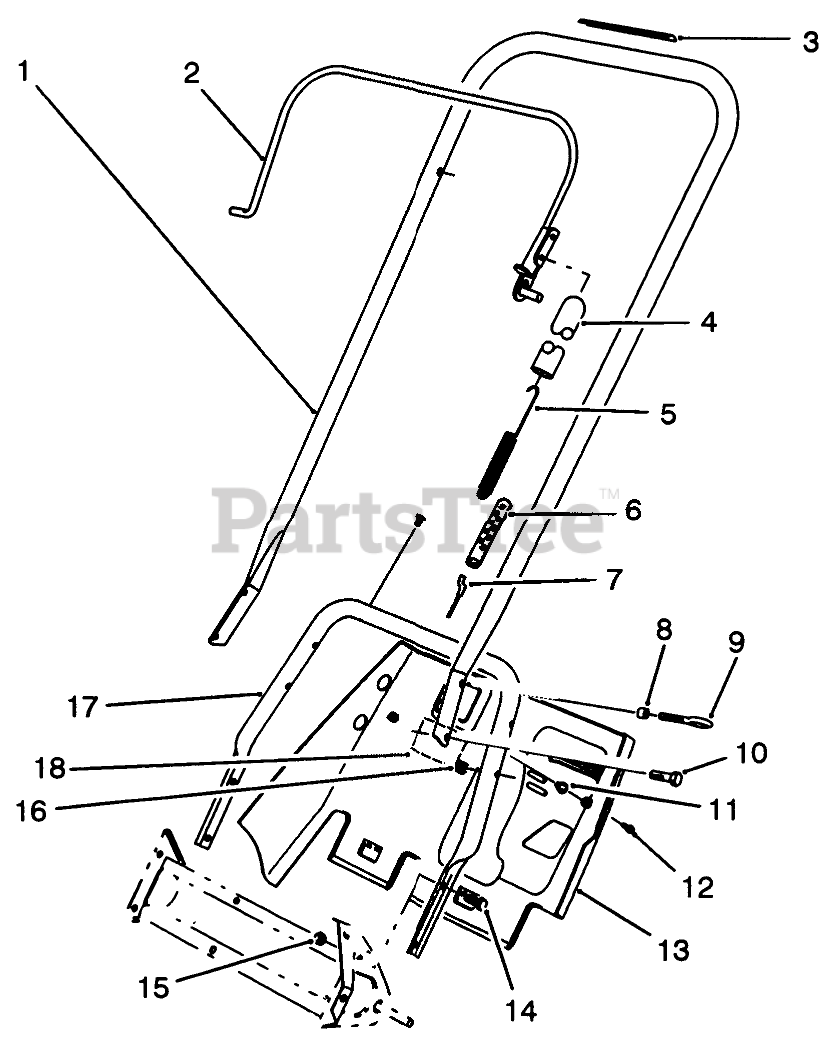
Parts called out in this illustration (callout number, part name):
1	Handle-Upper
2	Bail
3	DECAL - ROTOR DRIVE
4	COVER-SPRING
5	SPRING-CLUTCH
6	ADJUSTER-CABLE, CLUTCH
7	CABLE-CLUTCH
8	SPACER-BLADE, ROTOR
9	EYEBOLT
10	SCREW-HEX HD SLOT
11	EXPANSION TYPE FASTENER
12	SCREW-SHWH, THREAD FORMING
13	LOWER SHROUD
14	SCREW-HH
15	NUT-LOCK, NI
16	TINNERMAN NUT
17	Handle-Lower
18	Decal-Warning (Model No. 38196)
